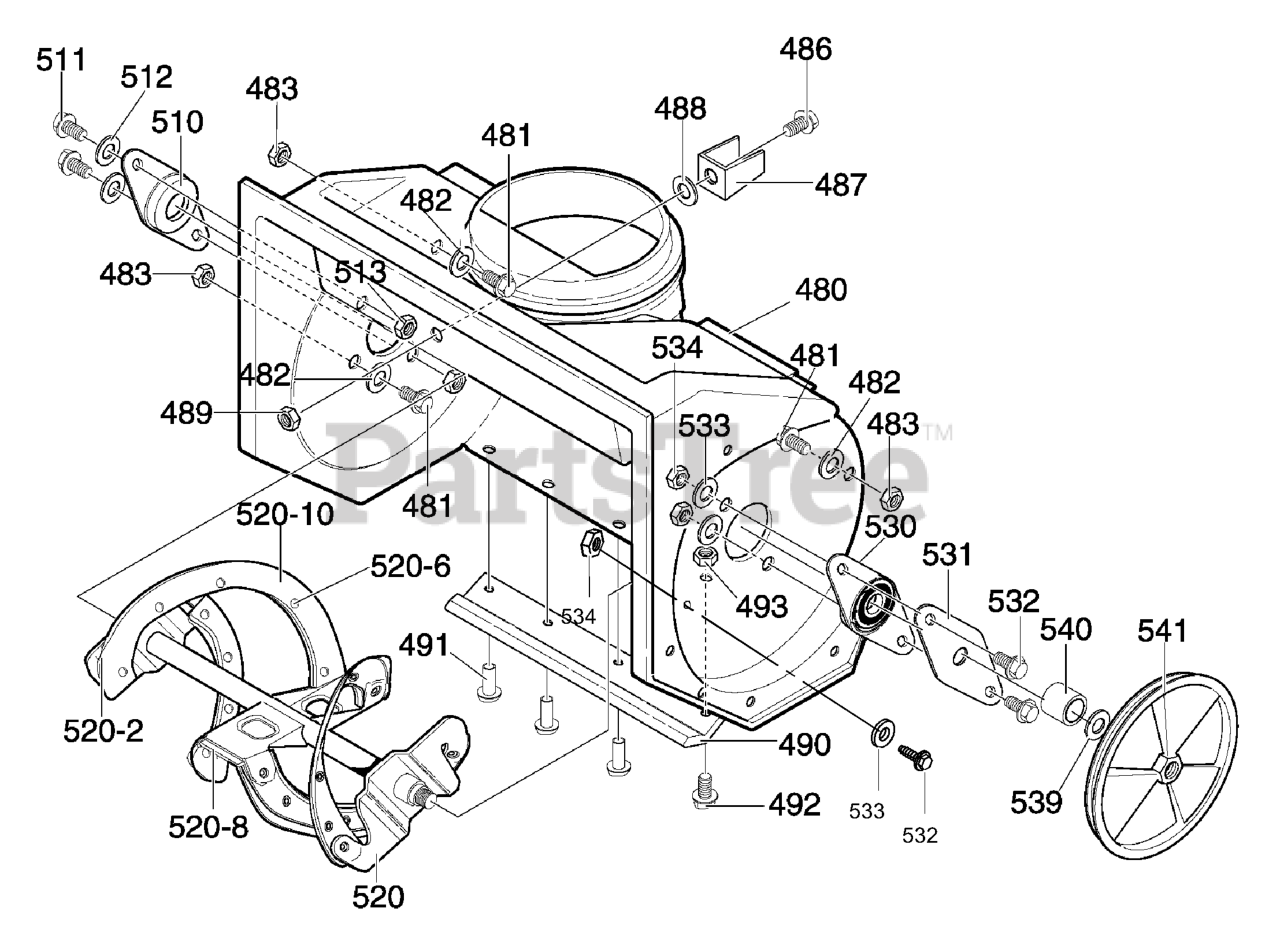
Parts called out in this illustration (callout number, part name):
480	HOUSING ASSEMBLY
481	SCREW, 1/4-20x.75
482	FLATWASHER
483	NUT, 1/4-20
486	SCREW, 1/4-20 x.63
487	BRACKET, STOP
488	FLATWASHER
489	NUT,1/4-20
490	SCRAPER BAR
491	RIVET
492	SCREW, 1/4-20x .75
493	NUT, 1/4-20
510	FLANGE BEARING
511	SCREW, 1/4-20x1.00
512	FLATWASHER
513	NUT, 1/4-20
520	AUGER ASSEMBLY
520-2	AUGER BLADE
520-6	RIVET
520-8	CENTER BLADE
520-10	AUGER & BLADE SUPPORT
530	BEARING & PLATE ASSY.
531	BEARING RETAINER
532	SCREW, 1/4-20x5/8
533	FLATWASHER,.281x.63x.065
534	NUT, 1/4-20 Reghexctrlk
539	FLATWASHER
540	SPACER, SLEEVE
541	PULLEY, POLY V -AUGER
